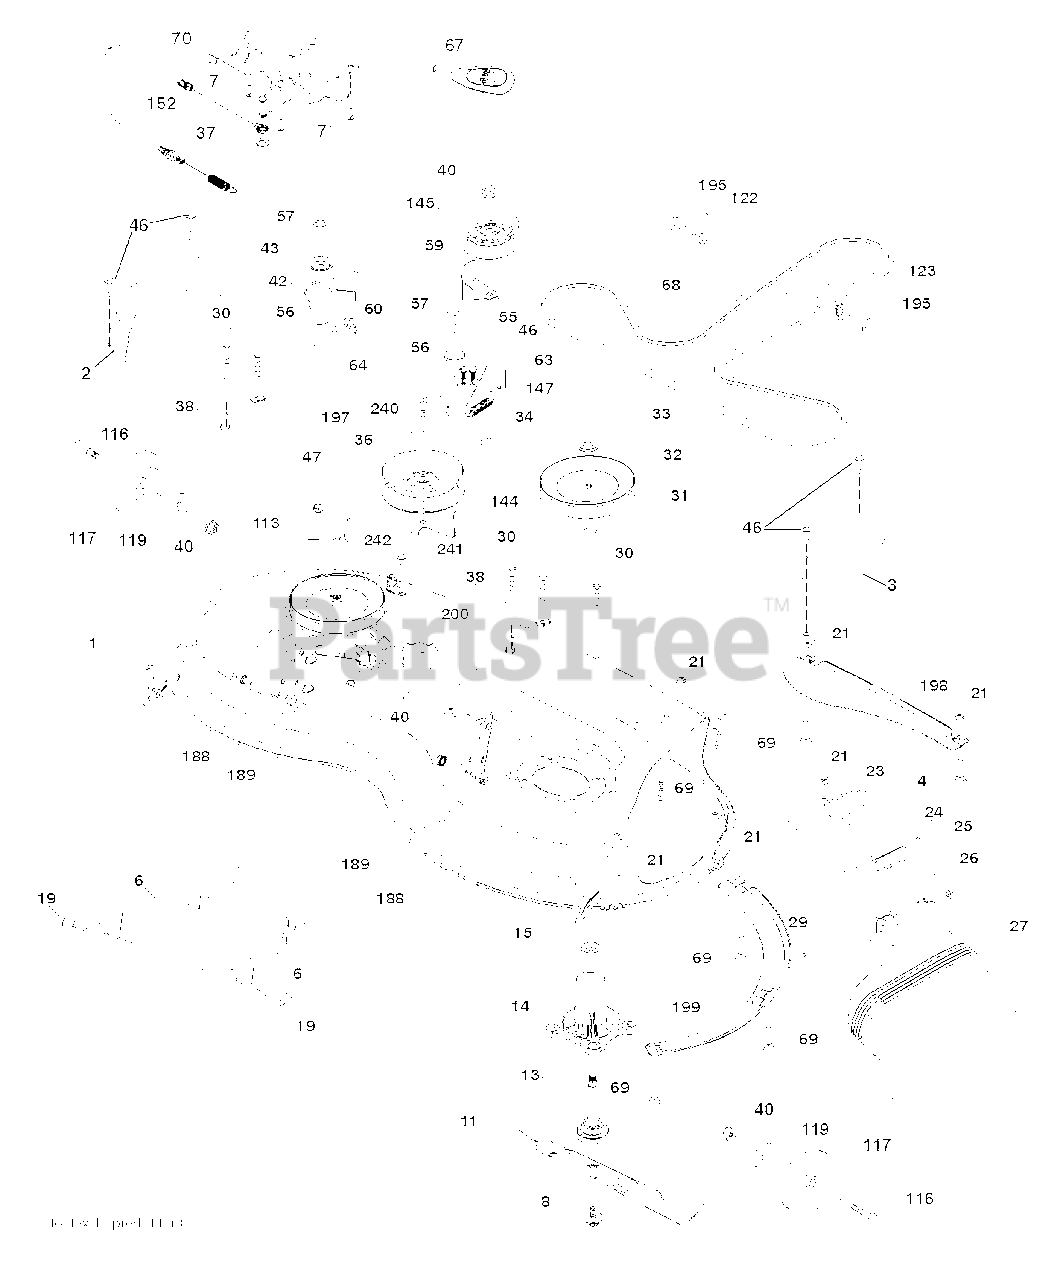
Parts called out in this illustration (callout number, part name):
1	DECK.SVC.46"
2	COVER.MANDREL.RH.46"
3	COVER.MANDREL.LH.46"
4	BOLT
6	ARM.SUSPENSION.MOWER.R
7	SCREW.#10 X 0.750.BOS
8	BOLT.WASHER.ASM.7/16-2
11	BLADE.MOWER.46".HI.LIFT
13	SHAFT.ASM.MDRL.N/GREASE.38
14	HOUSING.MANDREL.4PT.
19	BOLT.SHOULDER
21	LOCKNUT
23	BRKT.DEFLECTOR.38"2005+
24	CAP-SLEEVE LT
25	SPRING.TORSION.DEFLECT
26	NUT PUSH M
27	SHIELD.DEFLECTOR.MOWER.46"BLAC
29	ROD.HINGE
30	SCREW, WASHER HEAD
31	WASHER.SPACER.MANDREL
32	PULLEY.MANDREL.5.438.PD
33	NUT.FLANGE.LOCK.TOP
34	BOLT.3/8-16X1.50
36	PULLEY.IDLER.2006
37	WASHER
38	KEEPER.BELT.MANDREL.PULLEY
40	NUT LOCK FLG 3/8-16 UNC
42	SPRING.TORSION.BRAKE
43	SRPING.TORSION.RETAINE
46	SCREW.1/4-20X5/8
47	BRKT.CLUTCH.CABLE
56	SPACER.RETAINER
57	SCREW 3/8-16X1
59	GUARD, BELT
60	ARM BRAKE MOWER RH 38"
63	ARM BRAKE MOWER
64	LINKAGE BRAKE
67	HANDLE.CLUTCH.CABLE.LT
68	V-BELT
69	BOLT
70	CLUTCH.ASM.MANUAL.YT.PREDATORQ
113	BOLT.5/16HEX.WHS.HD
116	BOLT.SHOULDER.3/8-16X3-5/8.
117	WHEEL. GUAGE RALLY
119	WASHER
122	KEEPER BELT ENGINE LH
123	KEEPER BELT RH
144	KEEPER.BELT.MOWER
145	PULLEY.IDLER.48"PRIMARY
147	SPRING RETURN
152	CABLE.MECHANICAL.CLUTCH
188	STUD.FASTNER.W/ANTI-ROTATE
189	NUT LOCK HEX FLANGE 5/16-18
195	SCREW, 3/8-16X3/4
197	WASHER
198	BAFFLE CENTER FRONT
199	BAFFLE FRONT RH
200	WASHER.13/32 X 1 X 1/2.11GUARD
240	BOLT-HEX EAK
241	SCREW.TT.#10-32X.5.3/8.FLANGE
242	PORT.WASHOUT
